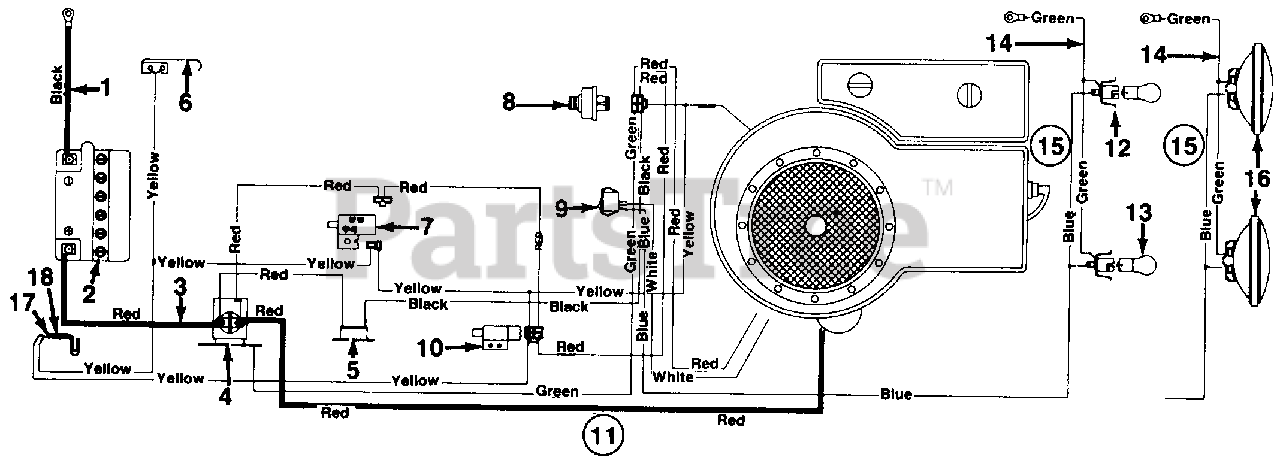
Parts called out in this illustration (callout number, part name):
1	Ground Wire
2	Battery
3	Electric Wire-8.0" Lg.
4	Solenoid
5	Circuit Breaker
6	Spring Switch
7	Safety Switch
8	Ignition Switch
9	Light Switch
10	Safety Switch
11	Harness
12	Socket
13	Bulb
14	Ground Wire
15	Headlight Harness
16	Headlight
17	Safety Switch
18	Safety Switch
